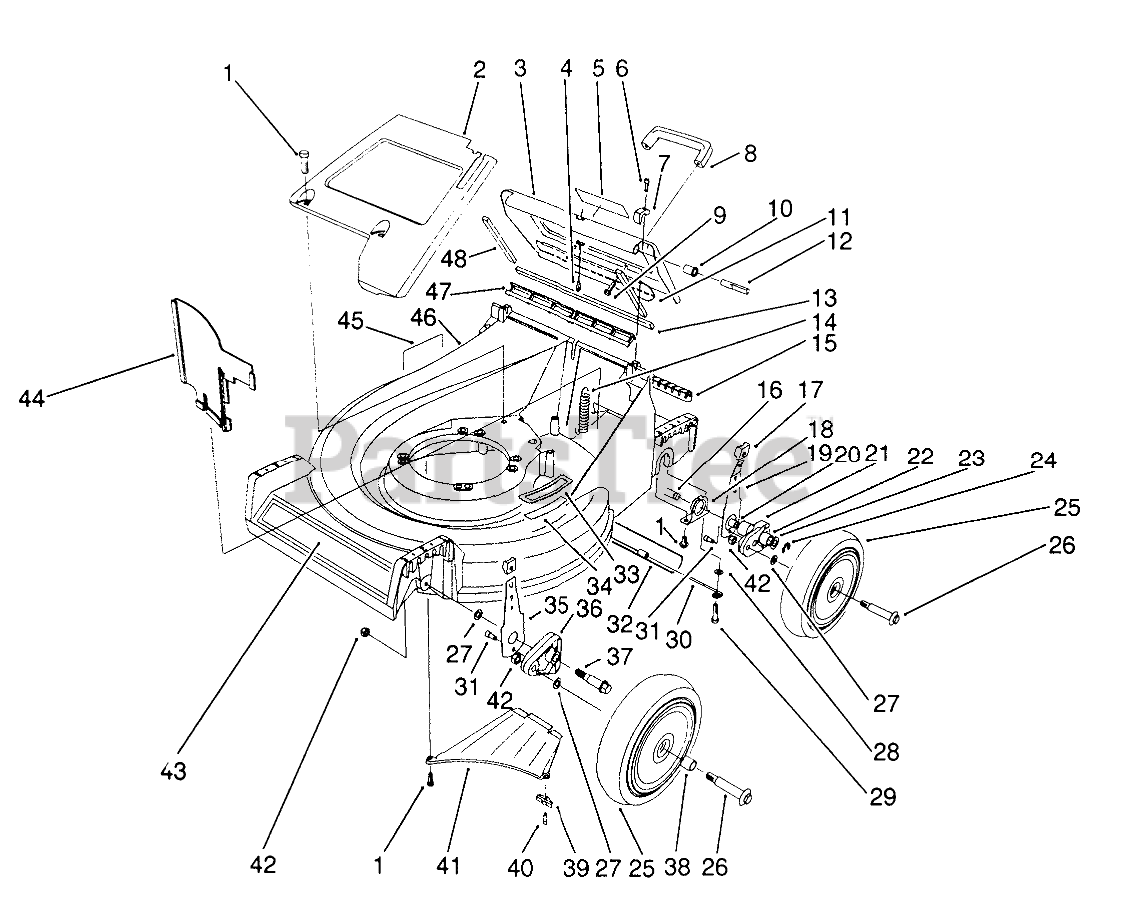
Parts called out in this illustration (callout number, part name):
1	SCREW-HWHTF
2	PaneI-Screen
3	Door-Discharge (Incl. Ref. #5, 11, 13, & 48)
4	DOOR CABLE
5	DECAL - WARNING
6	SCREW-HSH
7	HINGE CLAMP
8	HANDLE-DOOR
9	SCREW-HWH
10	DOOR BUSHING
11	DOOR - BRACE
12	HINGE PIN
13	DOOR END SEAL
14	EXTENSION-SPRING
15	ACCESS COVER
16	SHAFT - AXLE
17	KNOB-ARM
18	CAP-END
19	SPRING ARM ASM
20	BUSHING
21	Pivot Arm Ass-y (Incl. Ref. #20 & 22)
22	BUSHING
23	WASHER-ARM, PIVOT
24	RING-RETAINING
25	Wheel & Tire Ass-y (Incl. Ref. #38)
26	WHEEL BOLT
27	WASHER
28	WASHER-PLAIN
29	SCREW-SHOULDER
30	SHIELD HANGER
31	SCREW-HSH, THREAD FORMING
32	SHIELD - TRAILING
33	STEP PAD
34	STEP PAD DECAL
35	FRONT SPRING ARM ASM
36	ARM-PIVOT, FRONT
37	BOLT-SHOULDER
38	BUSHING
39	Bracket-Discharge
40	SCREW-HWHTF
41	Ramp Discharge
42	NUT-LOCK
43	DECAL - DECK
44	PANEL-VERTICAL
45	DECAL-DANGER
46	Housing Assembly (Incl. Ref. #29, 33, 34, & 45)
47	DOOR SEAL
48	DOOR SIDE SEAL
